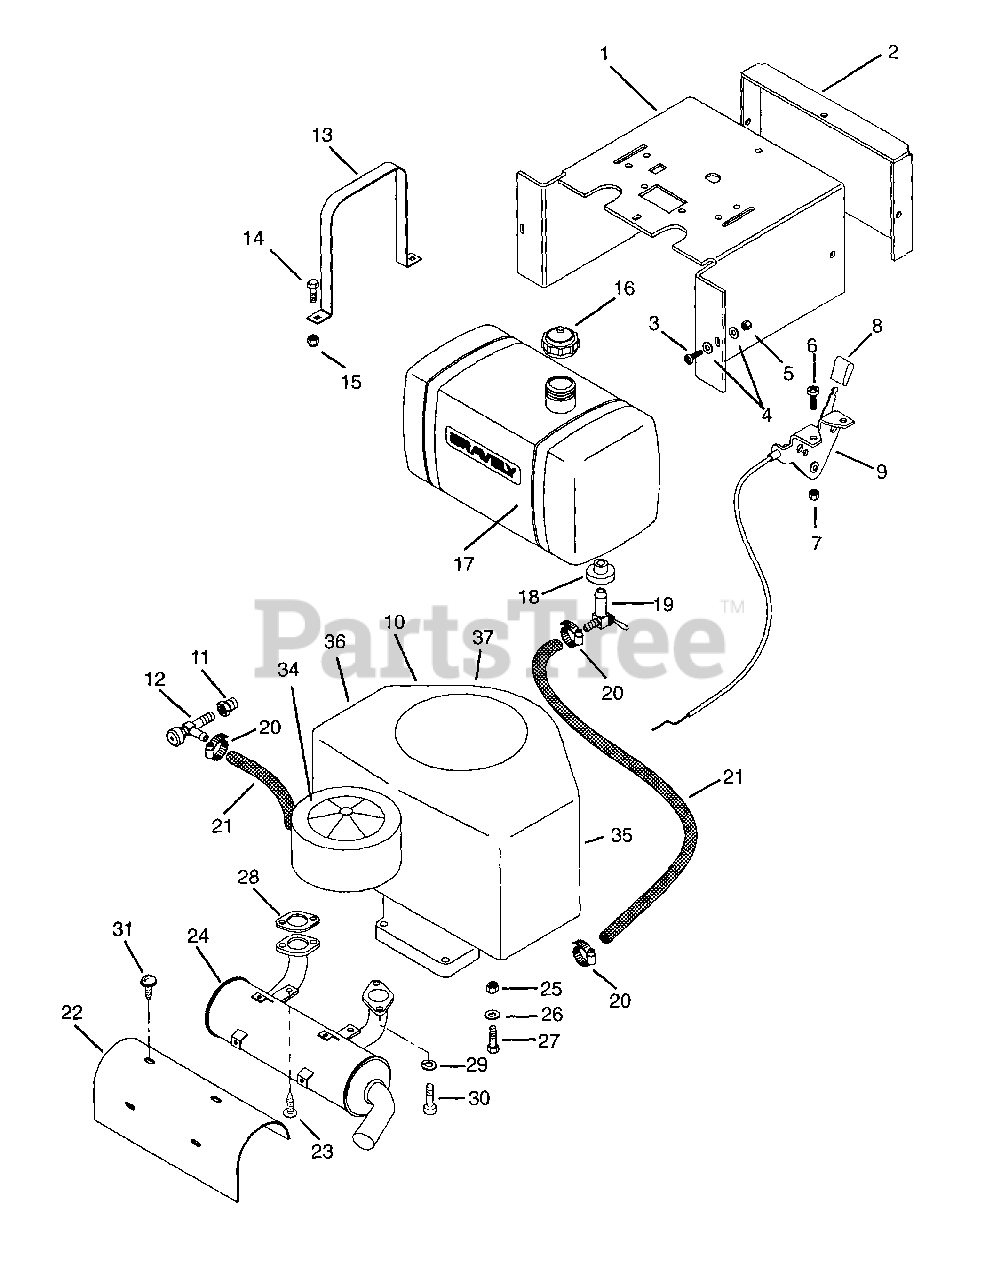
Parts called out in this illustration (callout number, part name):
1	Panel-Instrument
2	Cover-Instrument Panel
3	Screw-Machine-Hex Washer Head .25-20 x .75
4	Washer-Flat-Steel .281 x .620 x .065
5	Nut-Locking-Center .25-20
6	Screw-Machine-Hex Washer Head 10-24 x .50
7	Nut-Locking-Nylon w/insert 10-24
8	Knob
9	Assembly-Throttle Control
10	Engine-Kohler CV 18 HP
11	Adapter-Oil Drain
12	Cock-Oil Drain
13	Strap-Fuel Tank for 4.5 Gravely Fuel Tank
14	Bolt-Hex .25-20 x .75 Grade 5
15	Nut-Locking-Center .250-20
16	Cap-Fuel Tank
17	Tank-Fuel
18	Bushing
19	Valve-Ball Shut-Off
20	Hose Clamp
21	Gas Line-Bulk
22	Heat-Shield-Kohler CV18-25
23	Screw-Tapping M6-1 x 25MM
24	Muffler-Kohler CV18-CV25
25	Nut-Locking-Nylon .312-18 Grade 2
26	Washer-Flat-Steel .344 x .688 x .065
27	Bolt-Hex .31-18 x 1.50 Grade 5
28	Gasket-Exhaust
29	Washer-Locking .31 x .078
30	Bolt-Hex .31-18 x .75 Grade 5
31	Bolt-Hex .25-20 x 1.75 Grade 5
32	Spring-Compression .125 x .78 x 1.00
33	Washer-Flat-Steel .406 x .812 x .065
34	Air Filter
34	Air Filter Pre-Cleaner
35	Fuel Filter
36	Oil Filter
37	Spark Plug
